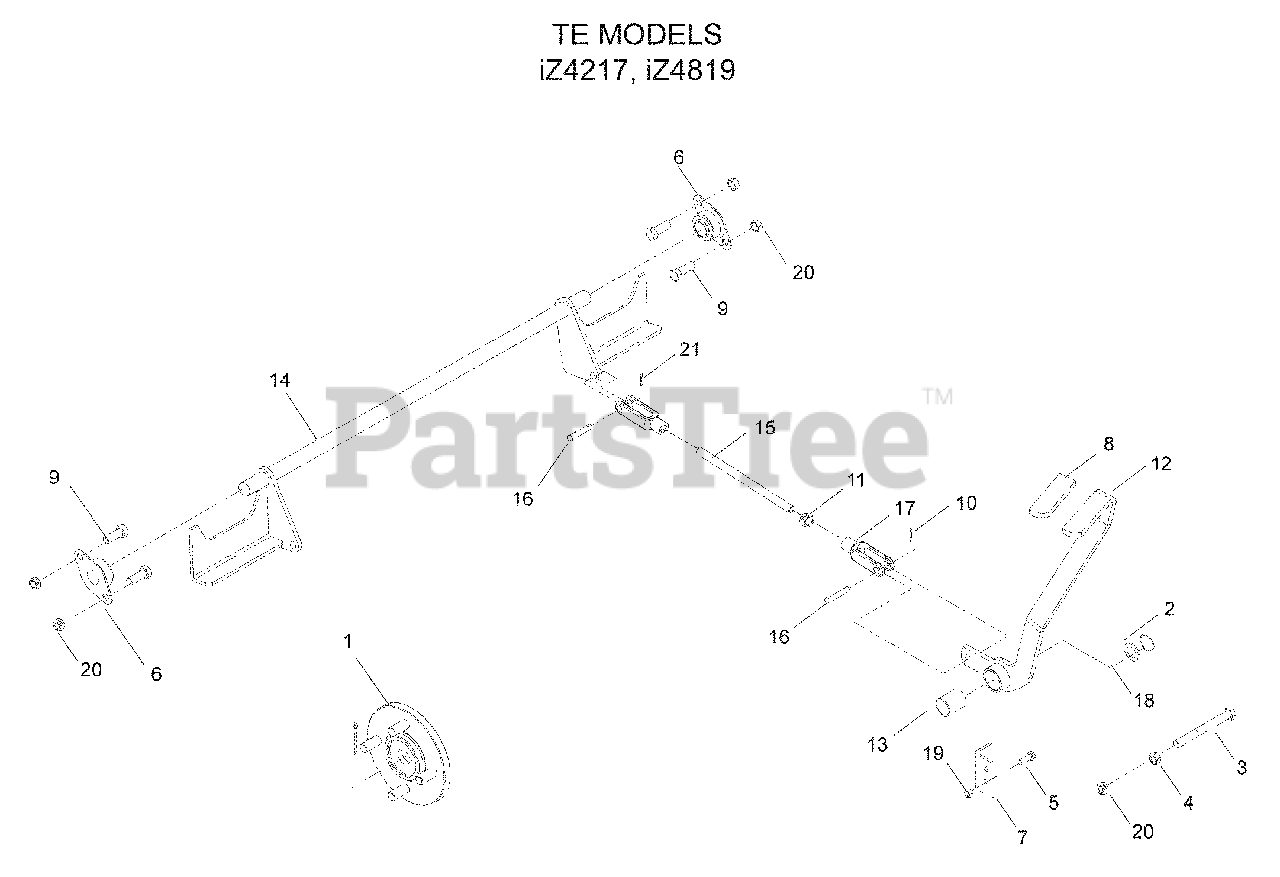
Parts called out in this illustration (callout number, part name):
2	RING, RETAINING EXT 7/8
3	HCS 3/8-16 x 2½
4	NUT 3/8-16 WHIZLK
5	HCS ¼-20 x ¾
6	BEARING, FLANGED
8	GRIP, PARK BRAKE
9	HCS 3/8-16 x 1
10	PIN, COTTER 1/8 x ¾
11	NUT 3/8-24 HEX NYLOC GR2
12	BRAKE LEVER
14	BRAKE CROSS SHAFT
16	PIN, CLEVIS 3/8 x 11/8
17	YOKE 3/8-24
19	NUT ¼-20 HEX NYLOC
20	NUT 3/8-16 HEX NYLOC
